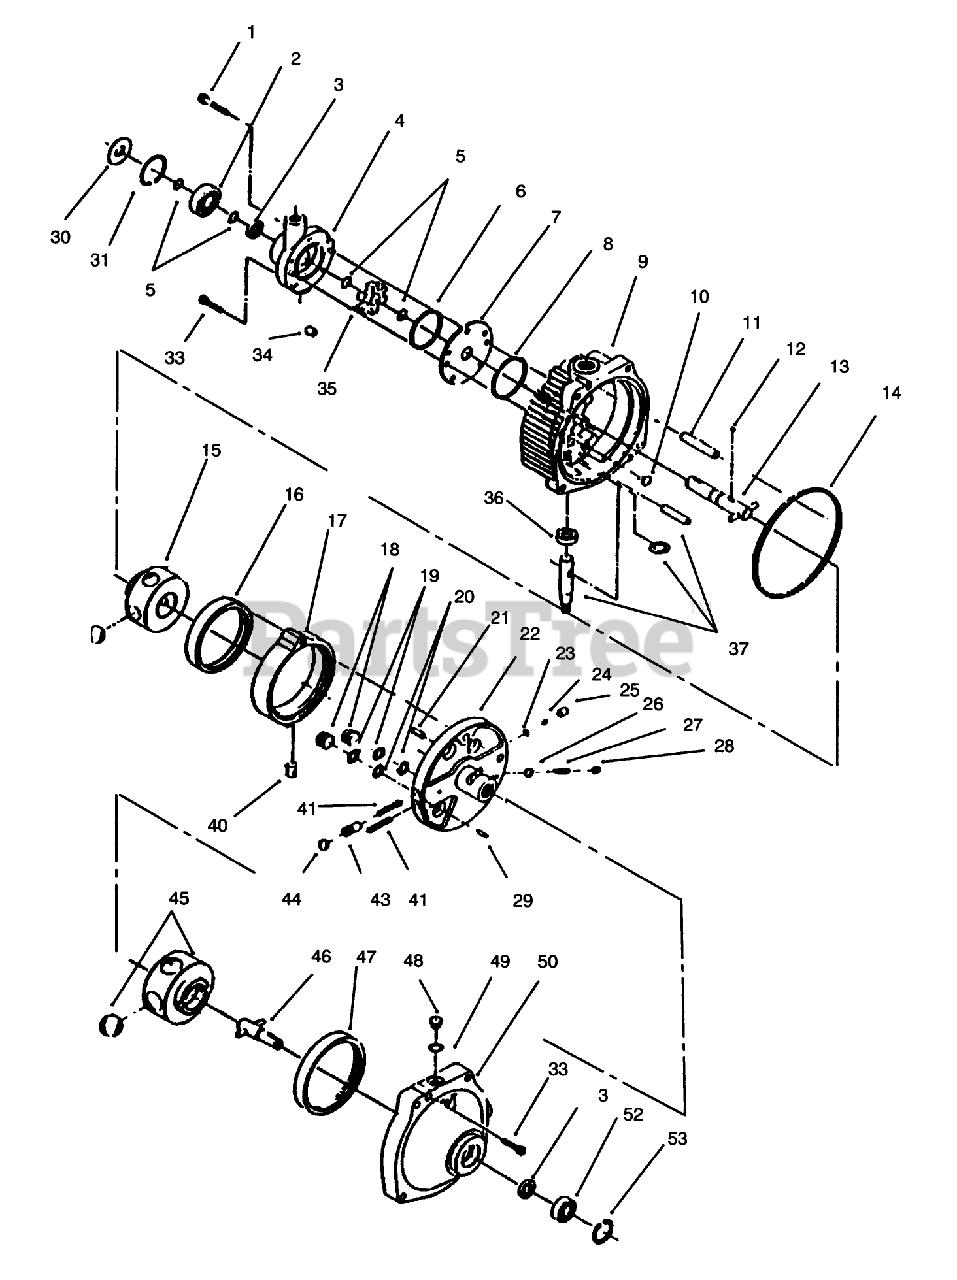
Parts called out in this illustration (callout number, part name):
1	CAPSCREW
2	BEARING
3	SEAL-OIL
4	Housing-Pump Assembly (Incl. Ref.# 3)
7	PLATE
9	Cover Assembly (Incl. Ref. #11,36 & 37)
10	BUTTON
13	SHAFT
15	ROTOR
16	PUMP-RACE
17	RING-CAM
18	PISTON
20	O-RING
22	Pintle Assembly (Inc. Ref. #1 18-21,23-29 41,43 & 44)
27	SPRING
30	SHIELD-GRASS
31	RETAINING-RING
33	SCREW-HH
35	CARRIER
36	SEAL-OIL
37	SHAFT KIT
40	INSERT
41	SPRING
45	ROTOR
46	SHAFT
48	Plug-Asm (Incl. Ref. #49)
49	O-RING
52	Bearing-Output
56	Ring-Cam (Incl. Ref.#16-17)
57	FITTING-HYDRAULIC 90 DEG
